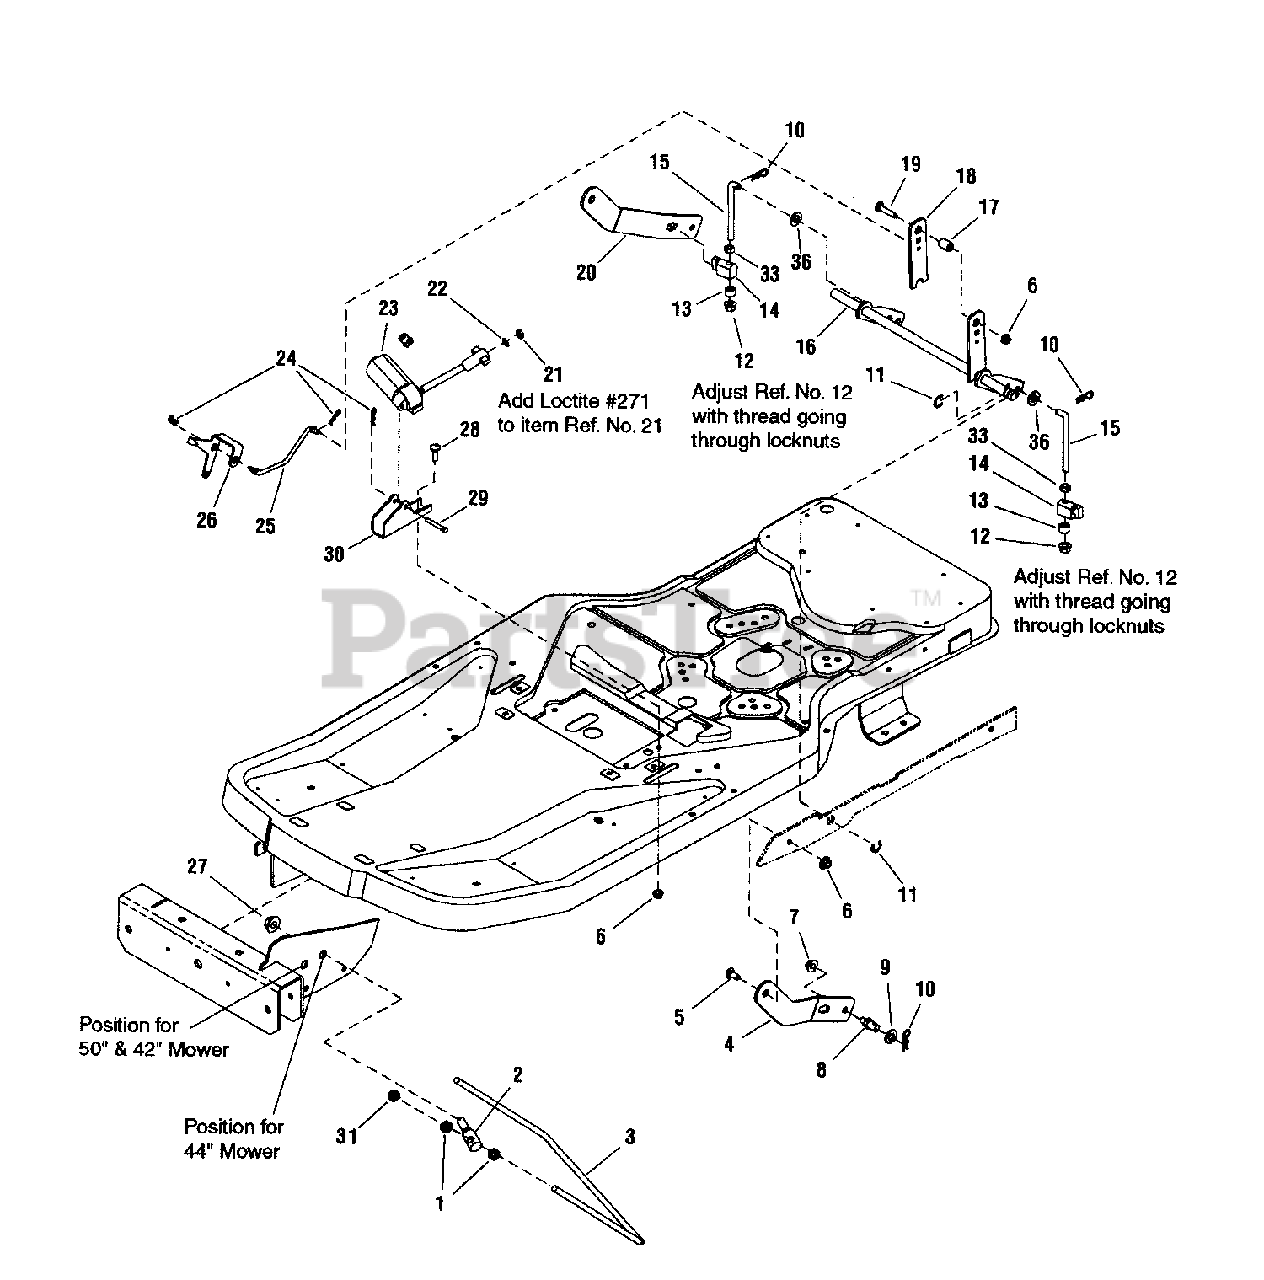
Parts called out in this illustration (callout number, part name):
1	NUT, 7/16-14 Hex Jam
2	TRUNNION, 1/2-13 Thread
3	ROD, Bail (7/16-14 Thread, 2 Places)
4	ARM, Mower Lift L.H.
5	SHOULDER BOLT, 5/16-18
6	NUT, 5/16-18 Hex Flange Lock, Small - Black
7	NUT, 3/8-16 Hex Center Lock Jam
8	PIN, 3/8-16 Threaded Shoulder
9	WASHER, 1/2" Flat (0.51 I.D. x 1.00 O.D. x .10 Thick)
10	CLIP, Hair Pin .093 Dia.
11	RING, External (Klipring) for .625 Dia. Shaft
12	NUT, 3/8-16 Hex Flange Nyloc
13	SPACER, .385 I.D. x .6697 O.D. x .455 Long, Powdered Metal
14	TRUNNION, Powdered Metal
15	ROD, Mower Lift, 3/8-16 Thread
16	WELDMENT, Lift Shaft
17	SPACER, .328 I.D. x .625 O.D. x .781 Long (Powdered metal)
18	ARM, Lift Trunnion
19	BOLT, 5/16-18 x 1-1/2" Round Head Short Square Neck, GR5
20	ARM, Mower Lift R.H.
21	NUT, 1/4-20 Hex, L.H. Thread
22	WASHER, 1/4" Flat (.27 I.D. x .62 O.D.)
23	MOTOR, Mini-Actuator (Electric)
24	HAIR PIN
25	ROD, Height-of-Cut Indicator
26	INDICATOR, Height-of-Cut
27	NUT, HEX FLANGE 1/2-13 Hex Flange Two Way Lock
28	BOLT, 5/16-18 x 1" Round Head Short Square Neck, GR5
29	PIN, Shear
30	BRACKET, Electric Motor Mount
31	NUT, 7/16-14 Hex
33	NUT, HEX 3/8-16 Hex
36	WASHER, .375 Flat (.41 I.D. x .87 O.D.)
